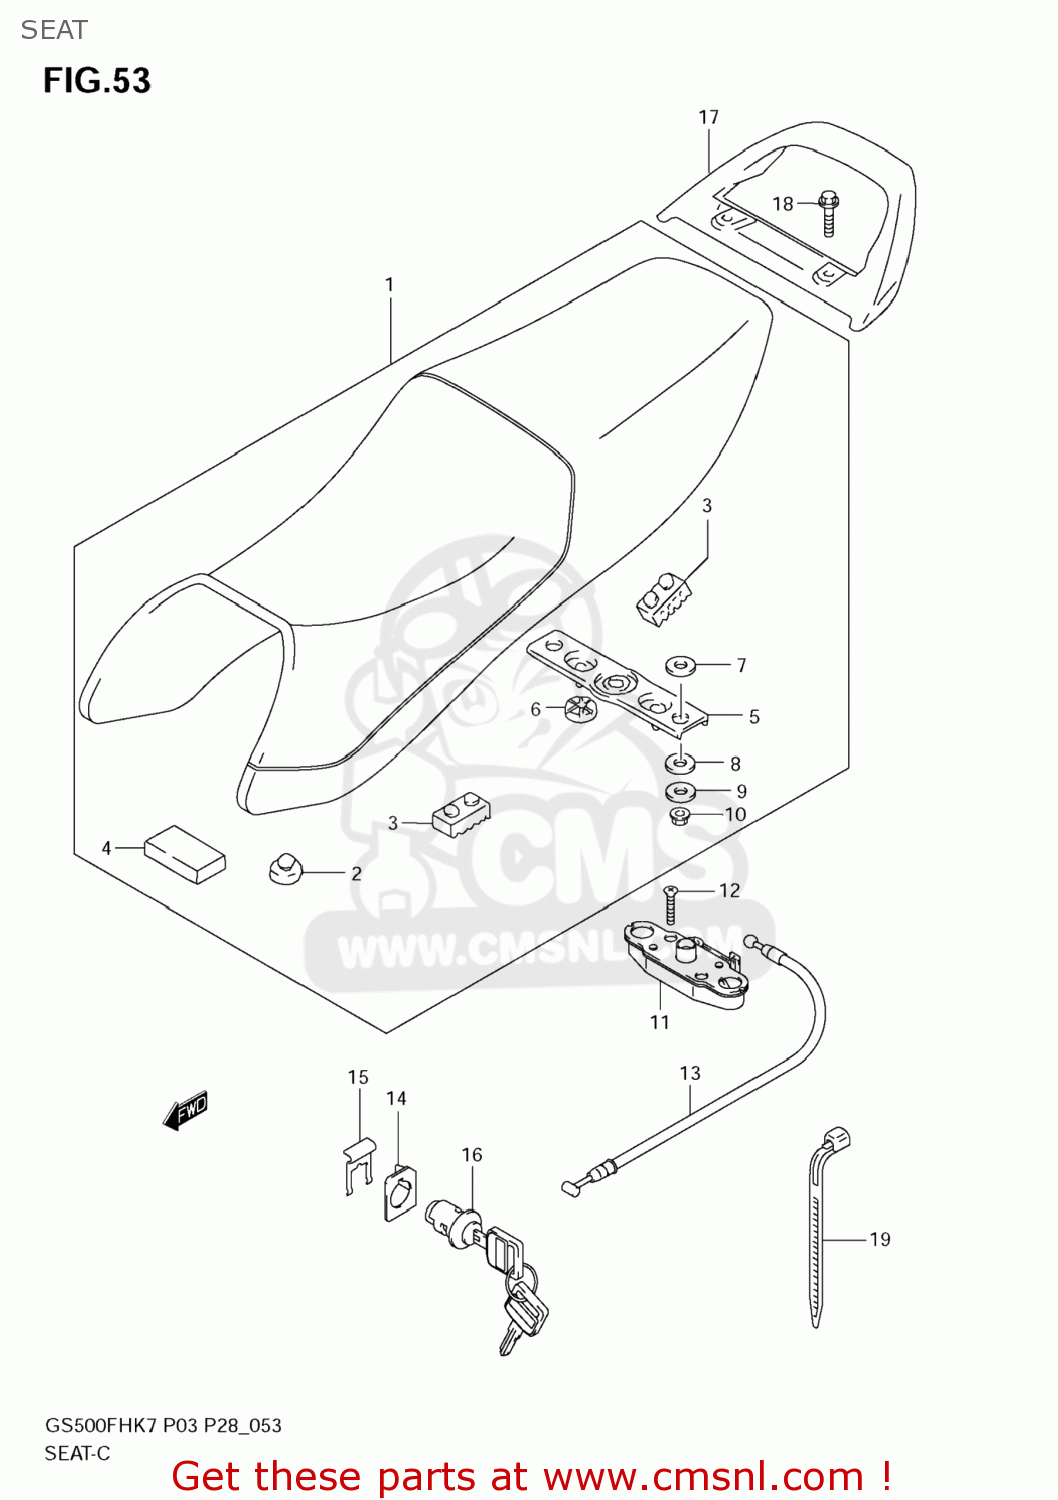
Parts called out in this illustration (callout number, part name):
1	SEAT SET (BLACK)
2	CUSHION,FRONT
3	CUSHION,RR
4	CUSHION, BATTERY STOPPER
5	STRIKER, SEAT LOCK
6	CUSHION, BOSS
7	CUSHION, STRIKER UPPER
8	CUSHION, STRIKER LOWER
9	WASHER
10	NUT
11	BRACKET,SEAT SUPPORT
12	BOLT
13	CABLE, SEAT LOCK
14	GUIDE,SEAT LOCK CABLE
15	PLATE,SEAT LOCK ASSY
16	LOCK SET,SEAT
17	HANDLE, PILLION RIDER (BLACK)
18	BOLT
19	CLAMP(L:165)
